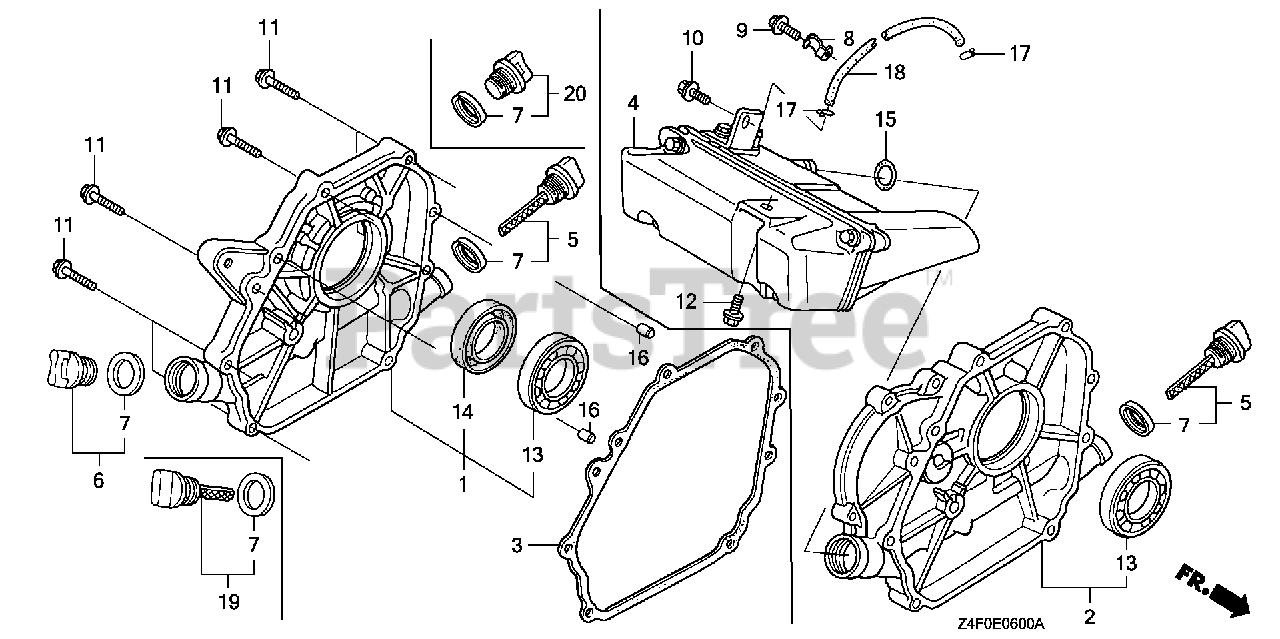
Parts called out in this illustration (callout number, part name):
1	COVER ASSY., CRANKCASE
3	GASKET, CASE COVER
5	CAP ASSY., OIL FILLER (GRAY)
6	CAP ASSY., OIL FILLER
7	GASKET, OIL FILLER CAP
11	BOLT, FLANGE (6X28) (CT200)
13	BEARING, RADIAL BALL
14	OIL SEAL (22X41X6)
16	PIN, DOWEL (8X14)
